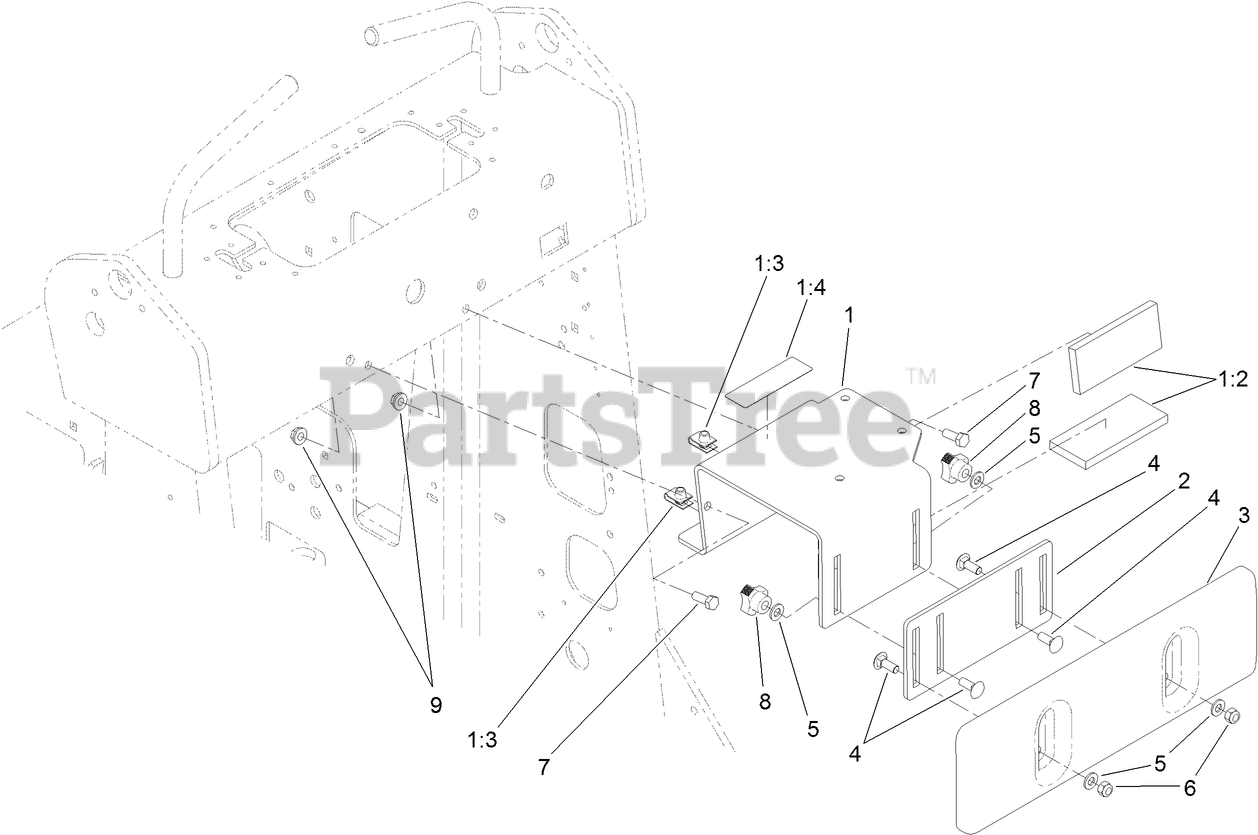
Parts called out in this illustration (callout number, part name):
1	THIGH SUPPORT BRACKET ASM
1:2	PAD-FOAM
1:3	NUT-CLIP, U
1:4	DECAL-MANUAL
2	PLATE-ADJUSTING
3	SUPPORT-THIGH
4	SCREW-CARR
5	WASHER-FLAT
6	NUT-LOCK, NI
7	SCREW-HH
8	Knob-Adjustment
9	NUT-HF
